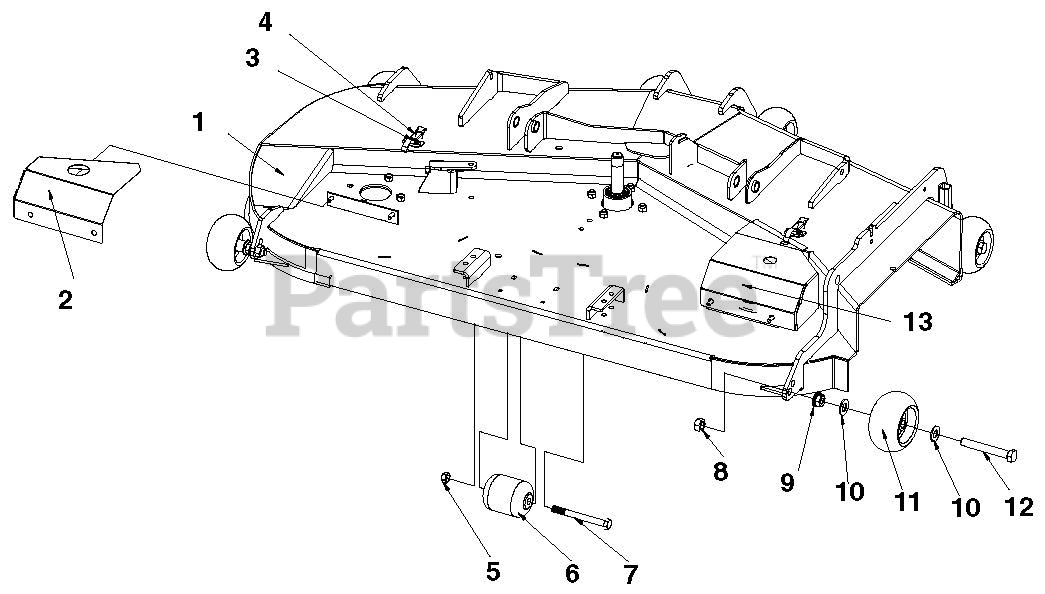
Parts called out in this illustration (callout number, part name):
1	ASSY, 60" DECK WITH DECALS ACM
1	ASSY, 66" DECK WITH DECALS ACM
2	SHIELD, LH 60" DECK BELT
2	SHIELD, BELT LEFT 66"
3	LATCH, OVERCENTER
4	RIVET, POP .188 X .375 STEEL
5	LOCKNUT, 1/2-13 CROWN Y
6	WHEEL, GAUGE 3.00 X 3.88 SYM
7	BOLT, 1/2-13X5.00 HEX 5 Y
8	LOCKNUT, 5/8-11 CROWN Y
9	LOCKNUT, 5/8-11 WHIZ Y
10	WASHER, .625X1.31X.098 FLAT Y
11	WHEEL, GAUGE 5.00 X 2.52
12	BOLT, 5/8-11X4.50 HEX 5 Y
13	SHIELD, RH 54" & 60" BELT
13	SHEILD, BELT RH 66"
